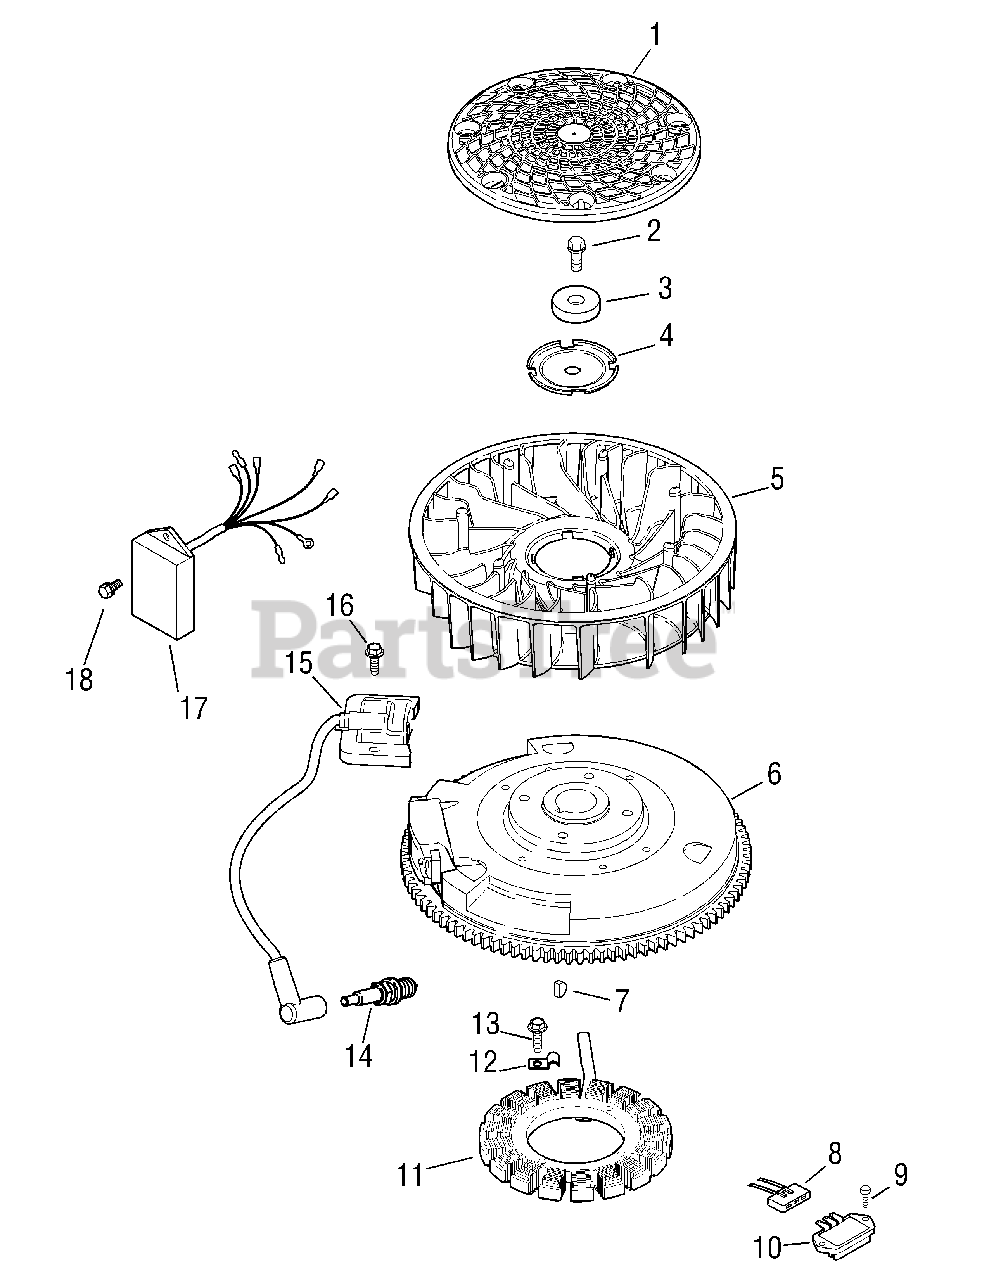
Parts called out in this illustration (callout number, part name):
1	Screen, grass
2	Screw, hex. flange M10x1.5x45
3	Washer, plain 3/8"
4	Plate, fan mounting
5	Fan
6	Flywheel (SLT 1554)
6	Flywheel (SLT 1550)
8	Connector (3 contact)
9	Screw, heavy hex. flange M5x0.8x16
10	Rectifier-regulator
11	Kit, 15 amp stator
12	Clip, cable (SLT 1554)
12	Clip, cable (SLT 1550)
13	Screw, hex. head thread forming M5x0.8x25
14	Spark plug
15	Module, ignition (SLT 1554)
15	Module, ignition (SLT 1550)
16	Screw, hex. flange thread forming M5x0.8x20
17	Module, speed advance (SLT 1554 only)
18	Screw, hex. flange thread forming (SLT 1554 only)
